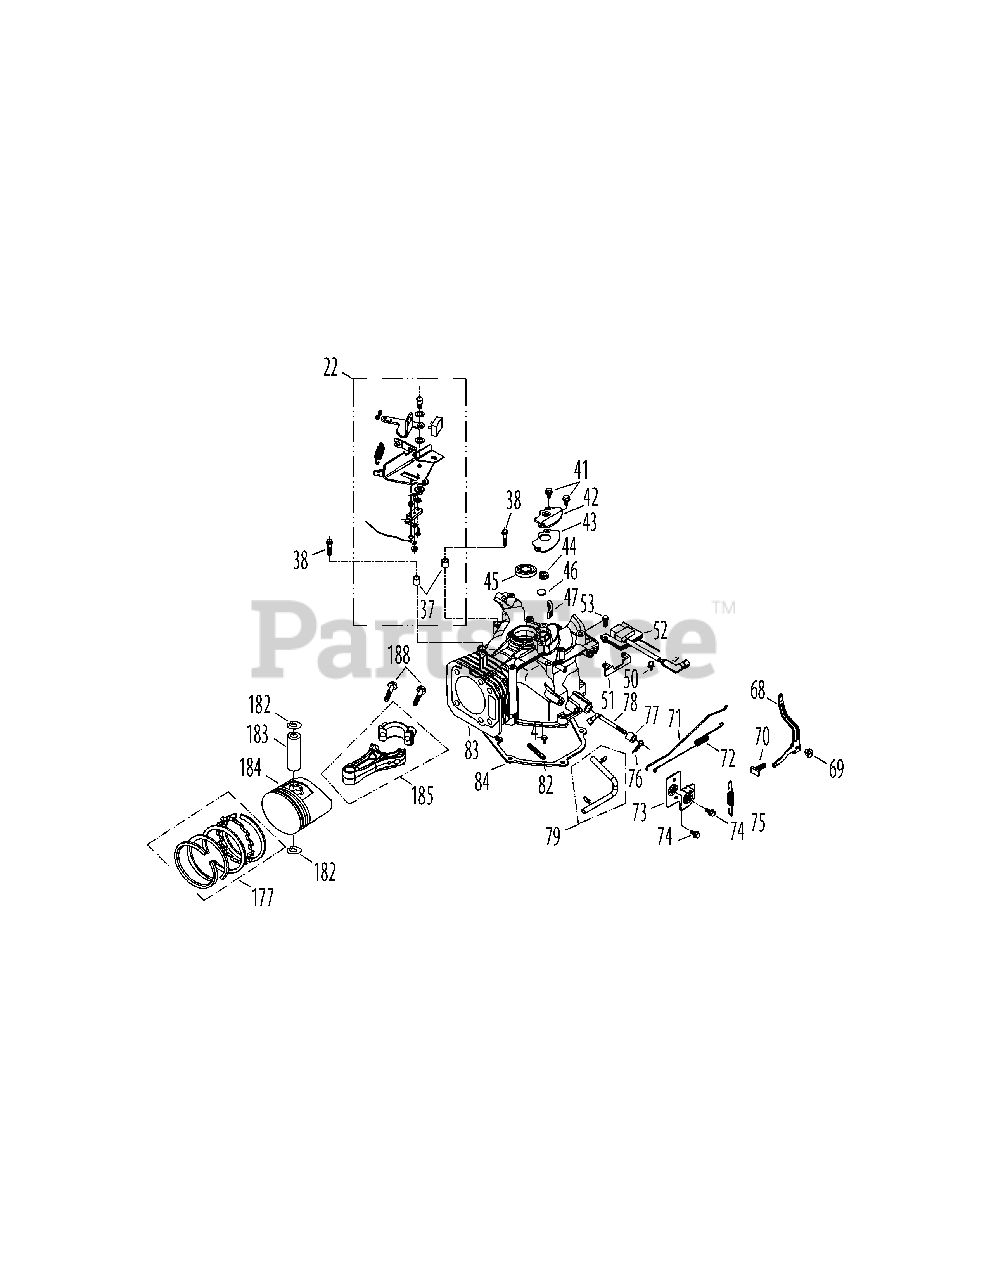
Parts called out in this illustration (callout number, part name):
22	Brake Assembly
37	Brake Spacer
38	Bolt M6X35
41	Bolt M6×14
42	Breather Cover Plate
43	Breather Gasket
44	Breather Spring
45	Lower Crankshaft Seal
46	Breather Valve
47	Breather Screen
50	Plastic Clamp 6.3×8
51	Ignition Coil Bracket
52	Ignition Coil Assembly
53	Bolt M6×18
68	Governor Arm Bracket
69	Governor Arm Nut M6
70	Governor Arm Bolt
71	Throttle Linkage
72	Throttle Linkage Spring
73	Component Bracket
74	Bolt M6×12
75	Governor Spring
76	Governor Cotter Pin
77	Governor Seal
78	Governor Arm Shaft
79	Breather Hose Assembly
82	Flexible Clamp
83	Crankcase Complete
84	Crankcase Cover Gasket
177	Piston Ring Set
182	Piston Pin Snap Ring
183	Piston Pin
185	Connecting Rod Assembly
188	Connecting Rod Bolt
